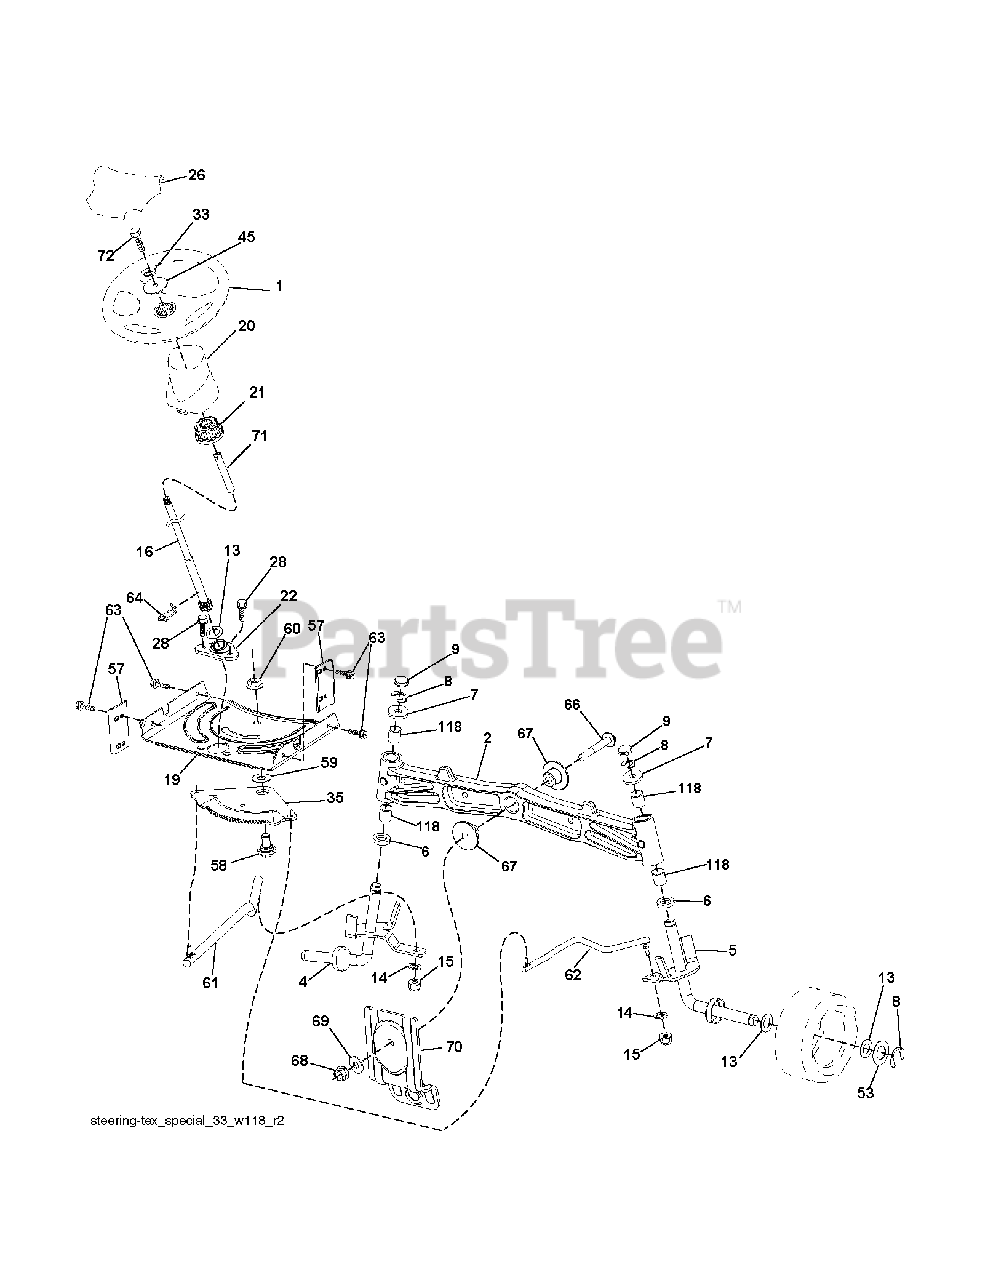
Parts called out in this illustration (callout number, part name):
1	WHEEL.STEER.HUSQ.SR.498.OVMLD
2	AXLE.SVC.ASM CAST IRON.TEX
4	SPINDLE.WELDED.LH.15"TEX
5	SPINDLE.WELDED.RH.15"T
6	THRUST WASHER
9	CAP.SPINDLE.BLACK
14	WASHER, LOCK 3/8
15	NUT CROWNLOCK 3/8-24
16	SHAFT.STEER.3/4.PLATED.TEX
19	PLATE.STEER.DDL.NLT/NG
20	STEERING.BOOT.HUSQ.LT
21	ADAPTER, WHEEL STNG..
22	STEERING.SUPT.LOWER.
26	INSERT.CAP.WHL.STRG.HUSQ.PREM
28	SCREW, 3/8-16X3/4
33	LOCKWASHER
35	GEAR.SECTOR.PLATE.DDL.
45	WASHER.11/32
53	WASHER.HARDENED
57	BRACKET.UPSTOP.TEX
58	BOLT.SHOULDER.SECTOR.P
59	WASHER.THURST.SECTOR.S
60	NUT FLANGE LOCK 5/8-11
61	DRAGLINK.LH.BALLSTUD.D
62	DRAGLINK.RH.BALLSTUD.D
63	SCREW
64	RETAINER.CLIP.SPRING.S
66	BOLT HEX FGHD 7/16-14 X 3 SERR
67	BUSHING.PM.FRONT AXLE
68	NUT.LOCK.FLANGE.7/16
69	WASHER.1.5X.505X.118
70	BRKT.DECK.SUSPENSION.F
71	SHAFT.EXTEN.STRG.SPLINE
72	BOLT 5/16-18 X 4 W/PATCH
118	BUSHING, AXLE CAST
